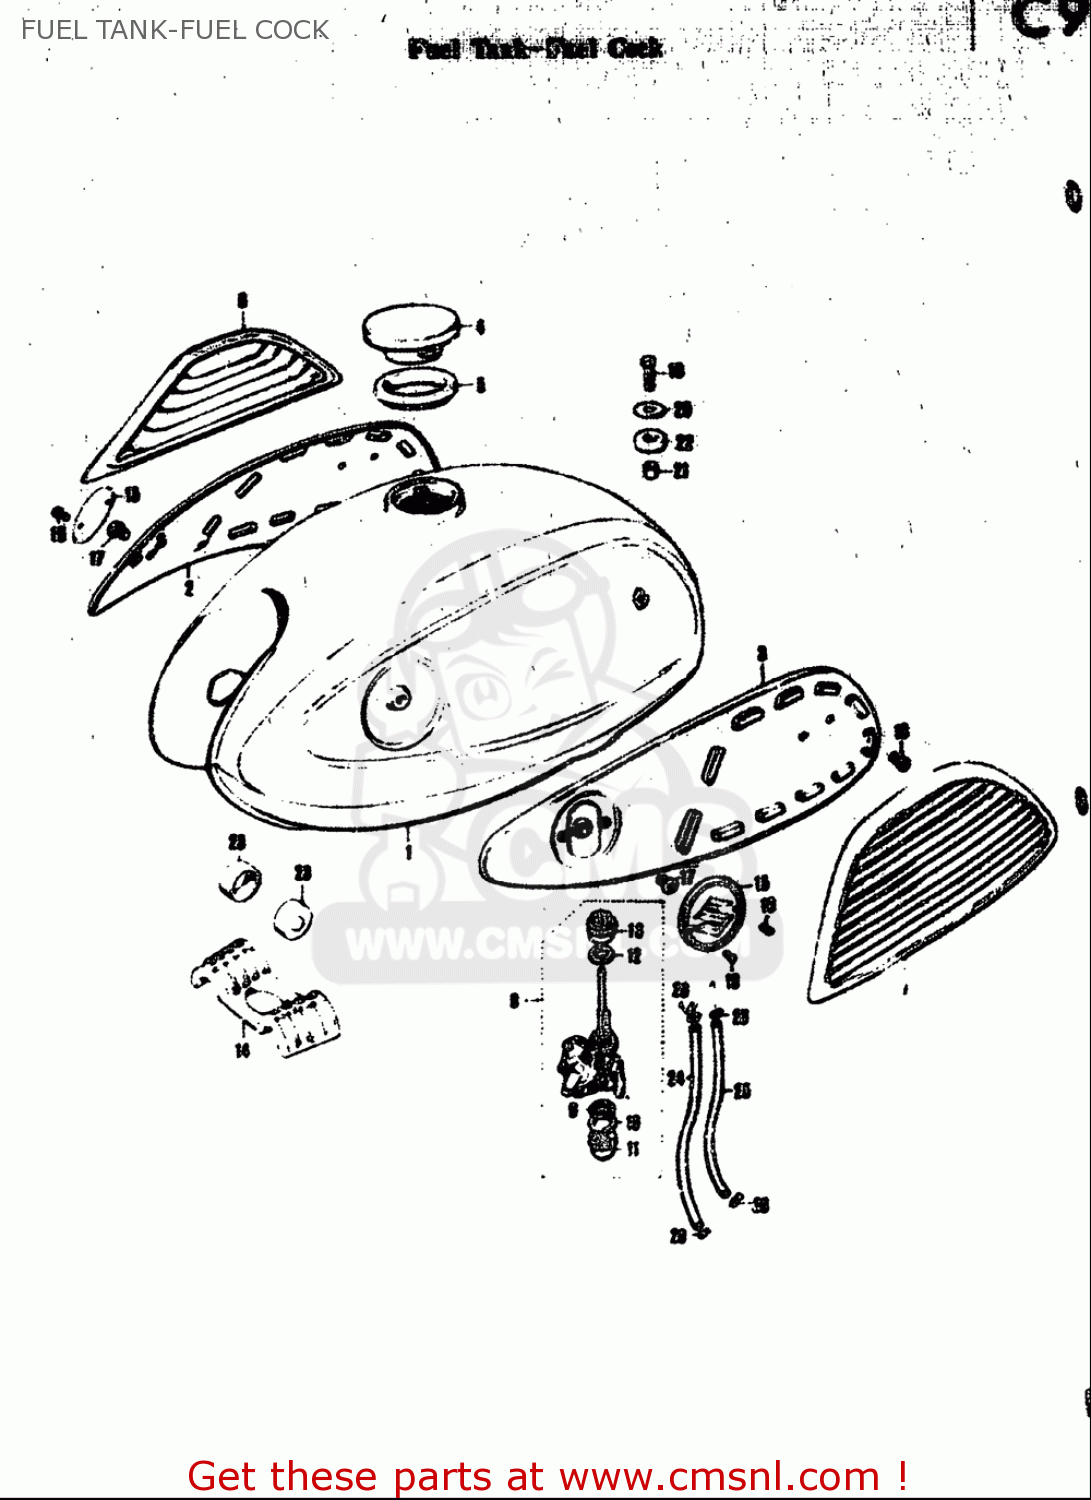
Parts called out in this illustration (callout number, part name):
8	COCK ASSY,FUEL
10	GASKET,CLEANER CUP (NAS)
12	GASKET,FUEL COCK (NAS)
18	SCREW(5X6)
20	WASHER(8.5X28X1.6)
21	SPACER(8.5X12X11)
24	HOSE(5X9X600)
25	HOSE(5X9X600)
